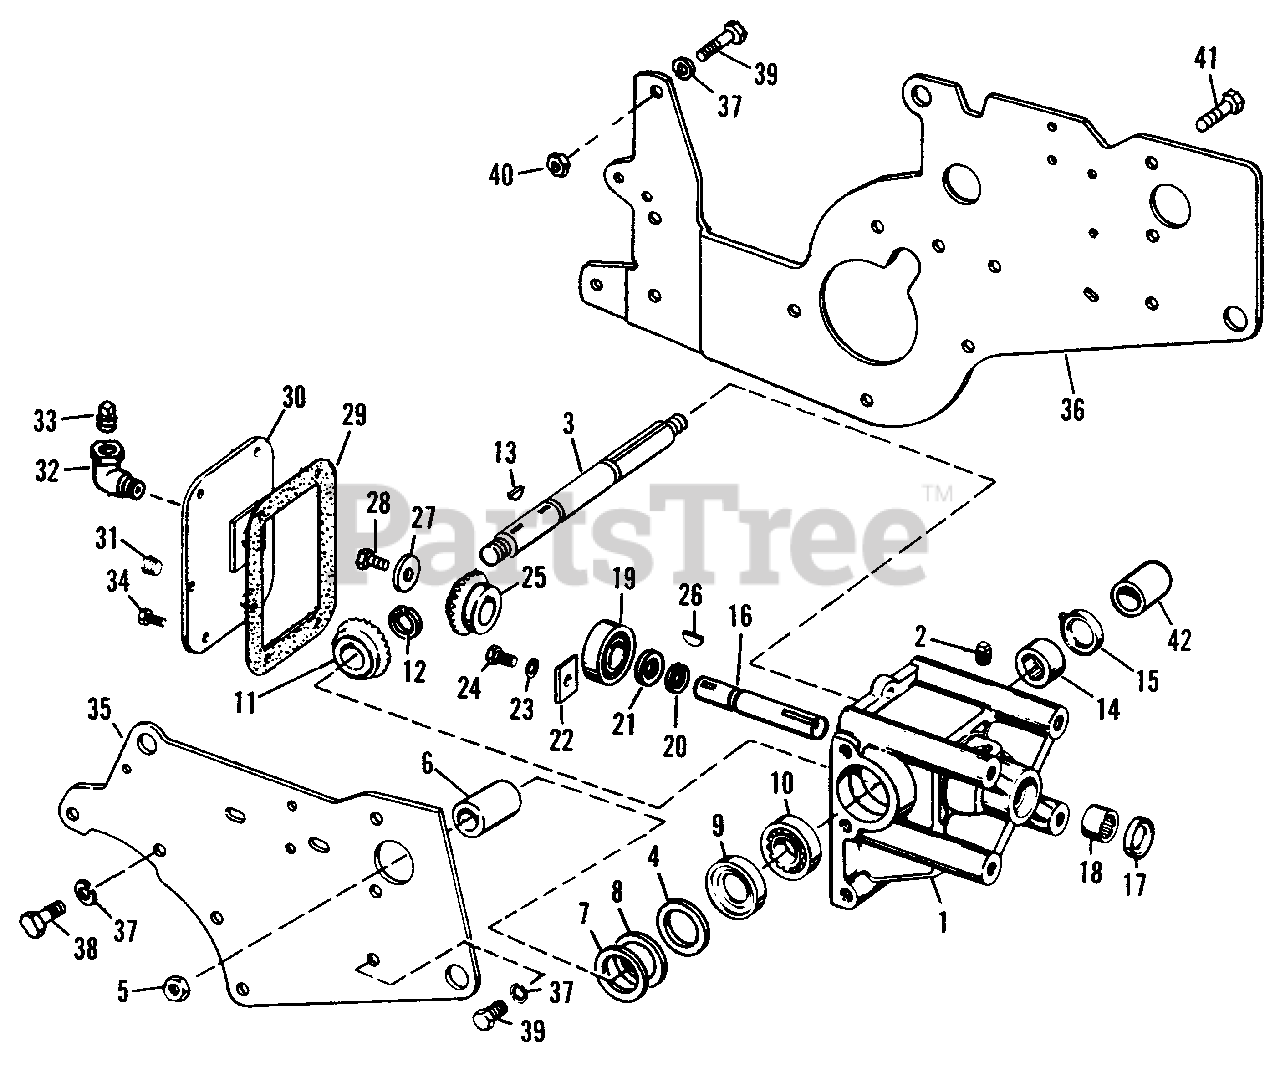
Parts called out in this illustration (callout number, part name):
1	Bevel Gear Housing, w/Bearings
2	Pipe Plug
3	Driven Shaft
5	Hex Jam Nut, 3/4"-16
7	Shim (As Required)
10	Ball Bearing
11	Bevel Driven Gear
12	Retaining Ring
14	Needle Bearing
16	Drive Shaft
18	Needle Bearing
19	Ball Bearing
20	Retaining Ring
22	Bearing Clamp Plate
23	Lockwasher, 5/16"
24	Hex Capscrew, 5/16"-18 x 5/8"
25	Bevel Driven Gear
28	Hex Capscrew, 5/16"-18 x 3/4"
30	Housing Cover Assembly
31	Pipe Plug, 1/4"
32	Street Elbow
33	Pipe Plug, 3/8"
34	Hex Capscrew, 1/4"-20 x 5/8"
35	R.H. Side Plate
36	L.H. Side Plate
37	Lockwasher, 7/16"
38	Hex Capscrew, 7/16"-14 x 1"
39	Hex Capscrew, 7/16"-14 x 1-1/4"
40	Full Hex Nut, 7/16"-14
41	Hex Capscrew, 7/16"-14 x 1-1/4"
